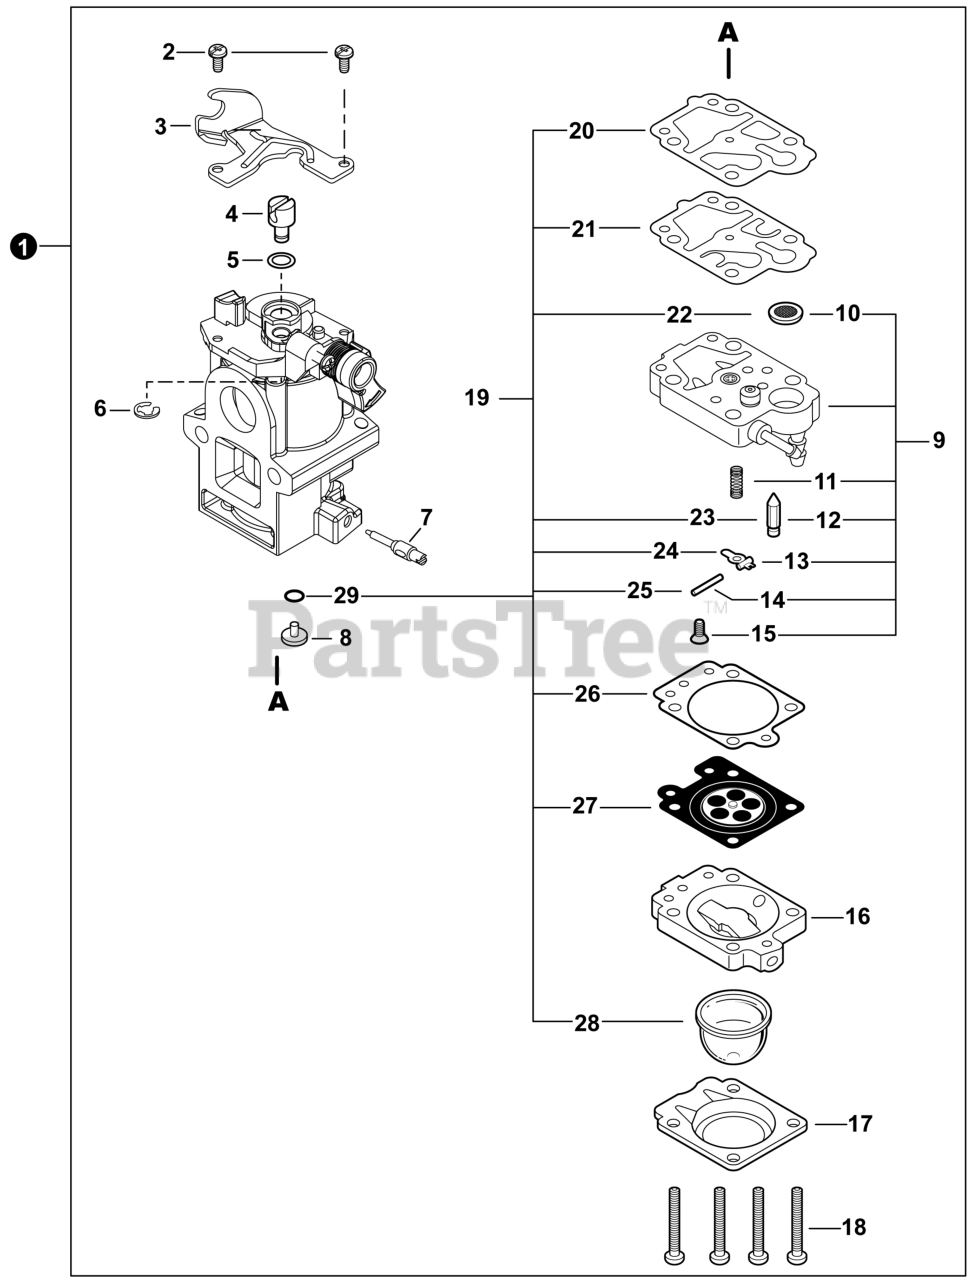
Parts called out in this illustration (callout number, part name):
1	CARBURETOR WYAB-1
3	BRACKET, THROTTLE CABLE
7	NEEDLE, MIXTURE
9	BODY ASSY, PUMP
10	SCREEN, FUEL INLET
11	SPRING, METERING LEVER
12	VALVE, INLET NEEDLE
13	LEVER, METERING
14	PIN, METERING LEVER
15	SCREW
16	BODY ASSY, PURGE
17	RETAINER, PURGE BULB
19	REPAIR KIT, CARBURETOR
20	GASKET, PUMP
21	DIAPHRAGM, FUEL PUMP
22	SCREEN, FUEL INLET
23	VALVE, INLET NEEDLE
24	LEVER, METERING
25	PIN, METERING LEVER
26	GASKET, METERING DIAPHRAGM
27	DIAPHRAGM, METERING
28	BULB, PURGE
29	O-RING
